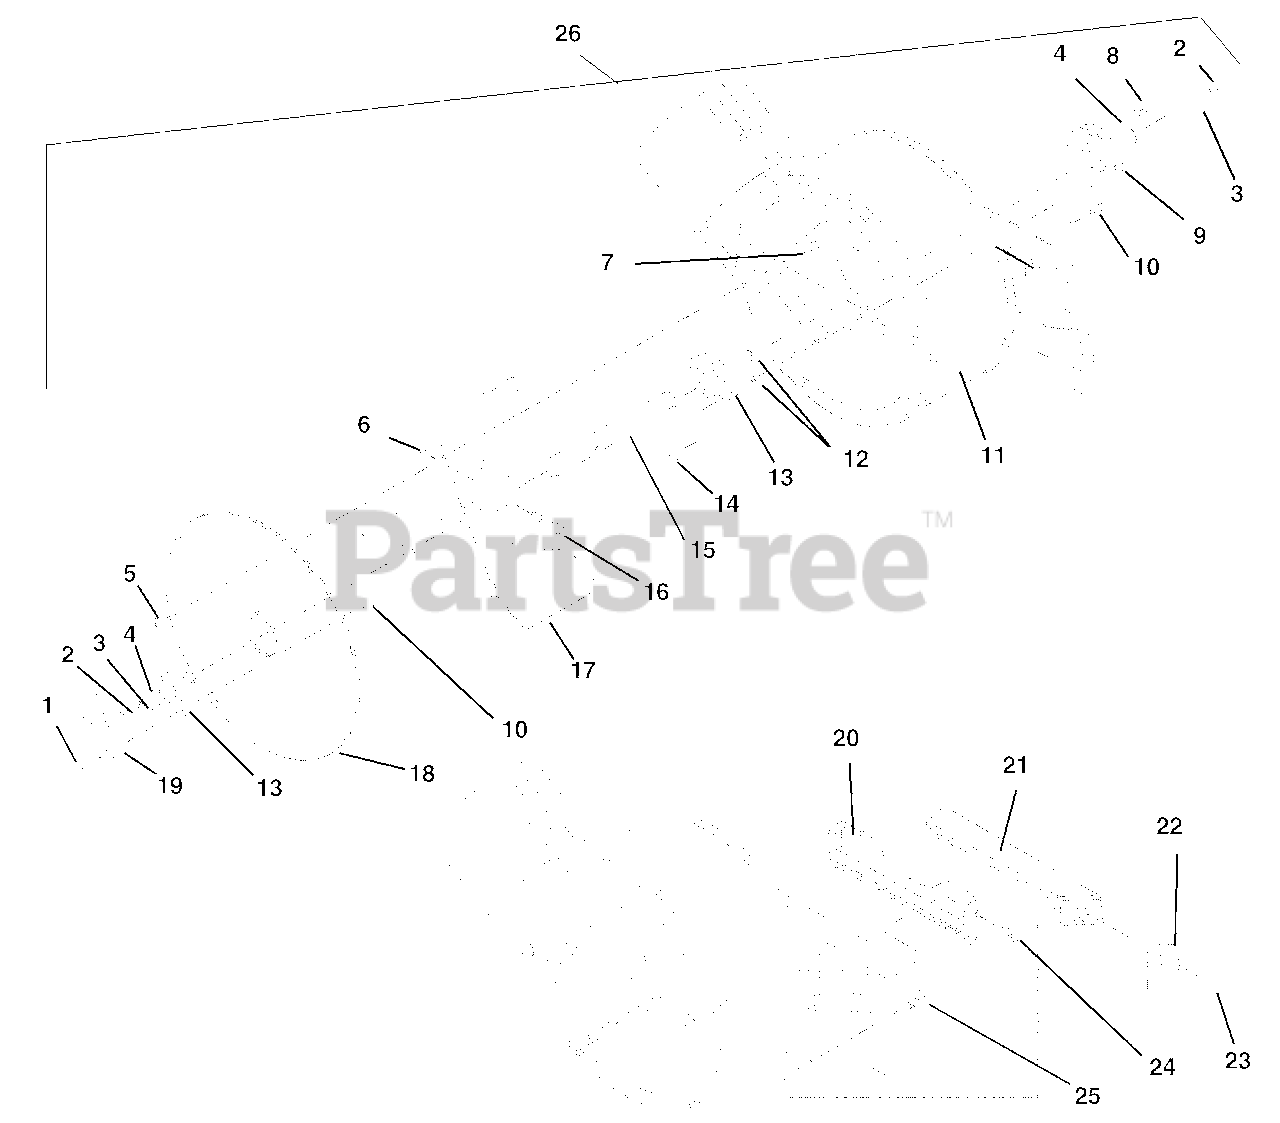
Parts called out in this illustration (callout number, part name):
1	@NUT-LK-NYL .312-18 YWZC
2	@BLT-HEX .25-20X.75 GR5 YWZC
3	@WSHR-LK .25X.062 REG YWZC
4	WSHR-FL-STL .265X1.370X.179
5	@NUT-LK-TOP-FLG .25-20 YWZC
6	@NUT-LK-CTR .31-18 YWZC
7	@BLT-RDHDSQNK .25-20X.50 G5YZ
8	KEY, SQ .25 X .38 X .25
9	PULLEY-DRIVEN, 3.50 DIA
10	@BLT-HEX .31-18X1.00 GR5 YWZC
11	WELDMENT, BLOWER HOUSING
12	@WSHR-FL-STL.312X.734X.065 YWZ
13	BEARING-2 BOLT X 1.00 SHAFT
14	@NUT-LK-TOP-FLG .31-18 YWZC
15	SHAFT-IMPELLER
16	@BLT-HEX .31-18X1.75 GR5 YWZC
17	IMPELLER COMPLETE
18	COVER, BEARING SUPPORT
19	COVER-BEARING
20	WMT. BLOWER MOUNT
21	GUARD, PUMP INLET
22	BAR, EXTENSION
23	@NUT-LK-TOP-FLG .25-20 YWZC
24	@SCR-TAP .25-20X.50 HWH TR YWZ
25	@BLT-RDHDSQNK .25-20X.75 G5YZ
26	ASSEMBLY, BLOWER HOUSING
